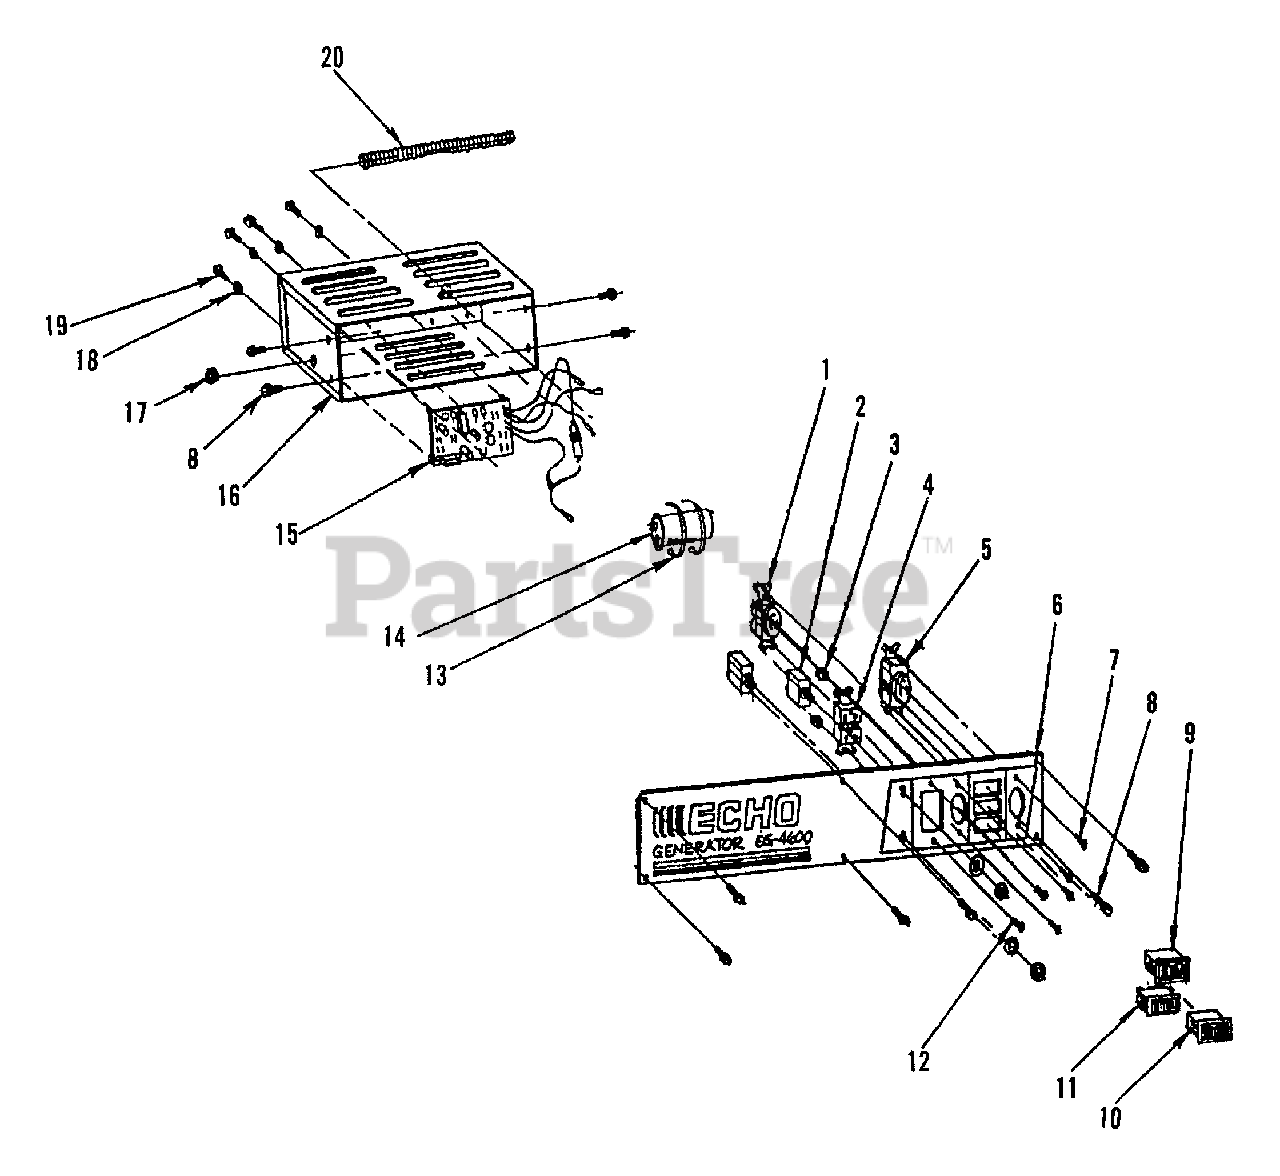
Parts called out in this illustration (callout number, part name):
1	LOCK, TWIST 20A/125V
2	BREAKER, CIRCUIT - 20A/250V
3	NUT - 8-32 -- KEPS
4	GFCI - 15A/125V
5	LOCK, TWIST 20A/240V
6	PANEL, SILK SCREENED
7	6-32X3/8 RHS
8	SCREW - 10-24
9	SWITCH, IGNITION
10	SWITCH, FULL POWER
11	SWITCH, ECHO-MISER
12	8-32X3/8 RHS
13	TIE, CABLE
14	CAPACITOR - 50UF 370V
15	CIRCUIT, ECHO-MIZER
16	BOX, CONTROL
17	GROMMET
18	LOCKWASHER - 6
19	6-32X 1/4 RHS
20	CONDUIT - 12"
